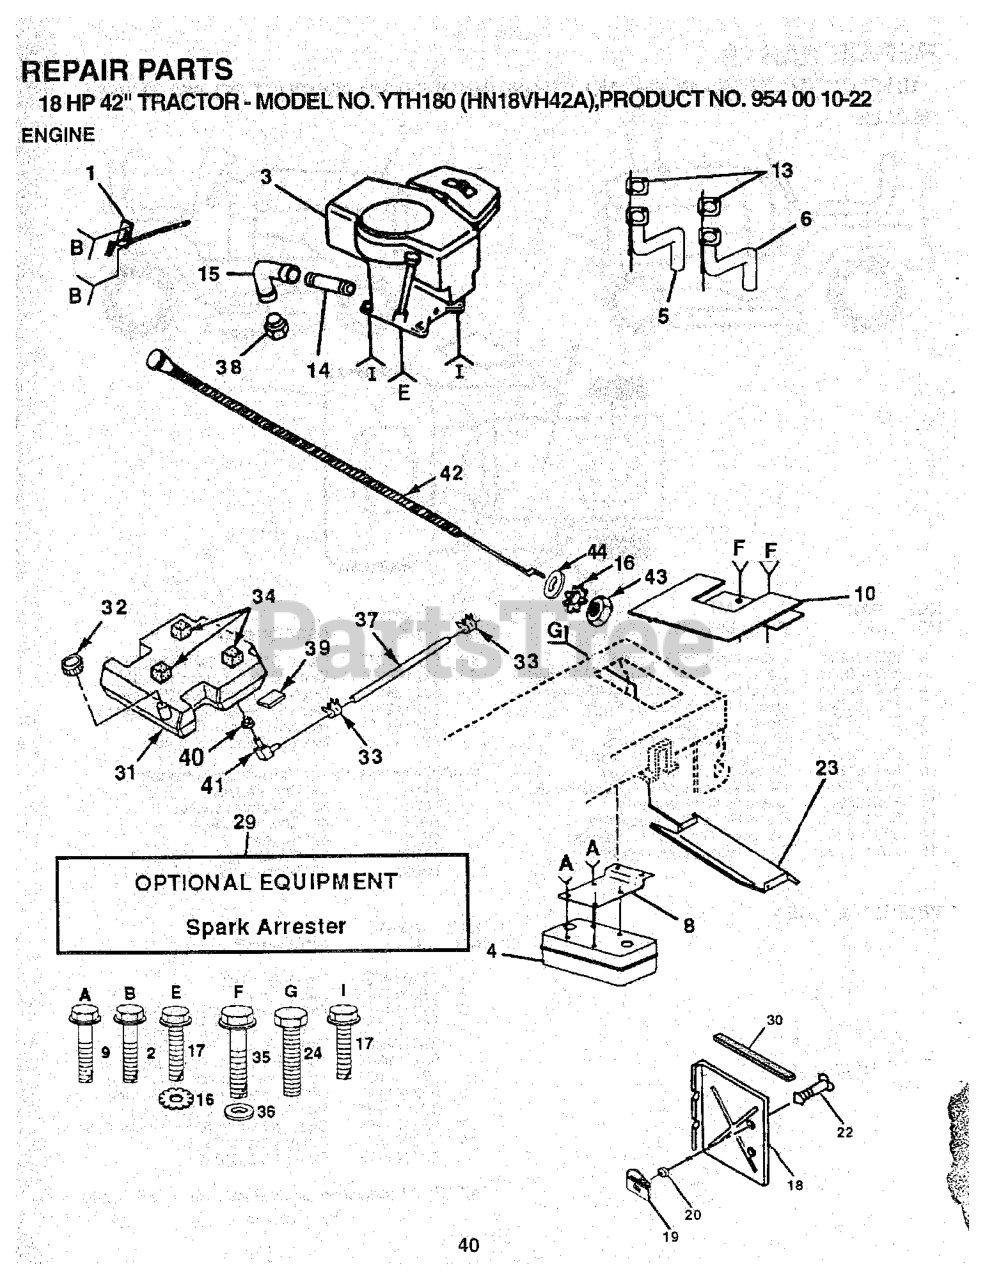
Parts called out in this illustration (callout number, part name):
1	THROTTLE CONTROL
2	SCREW LT
4	MUFFLER
5	TUBE ASSY EXH LH
6	TUBE ASSY EXH RH
8	BRACKET MUFFLER
9	SCREW ST
10	HEAT SHIELD
14	Nipple, Pipe 3/8 NPT x 4-1/2
15	ELBOW
16	LOCKWASHER
17	SCREW
18	HEAT SHIELD
19	RECEPTACLE LT
20	RETAINER LT
22	STUD 1/4 TURN
23	HEAT SHIELD
29	KIT.SPARK ARRESTOR 794945 B&S
30	FOAM-STRIP LT
31	FUEL TANK
32	FUEL CAP
33	HOSE CLAMP
34	PAD-SPACER LT
35	SCREW.THDROL.5/16-18X3/4.TTY
36	WASHER
37	FUEL LINE 54"
39	PAD IDLER TI
40	BUSHING OUTLET T
41	STEM FUEL TANK
42	CHOKE CONTROL
43	NUT
44	WASHER
